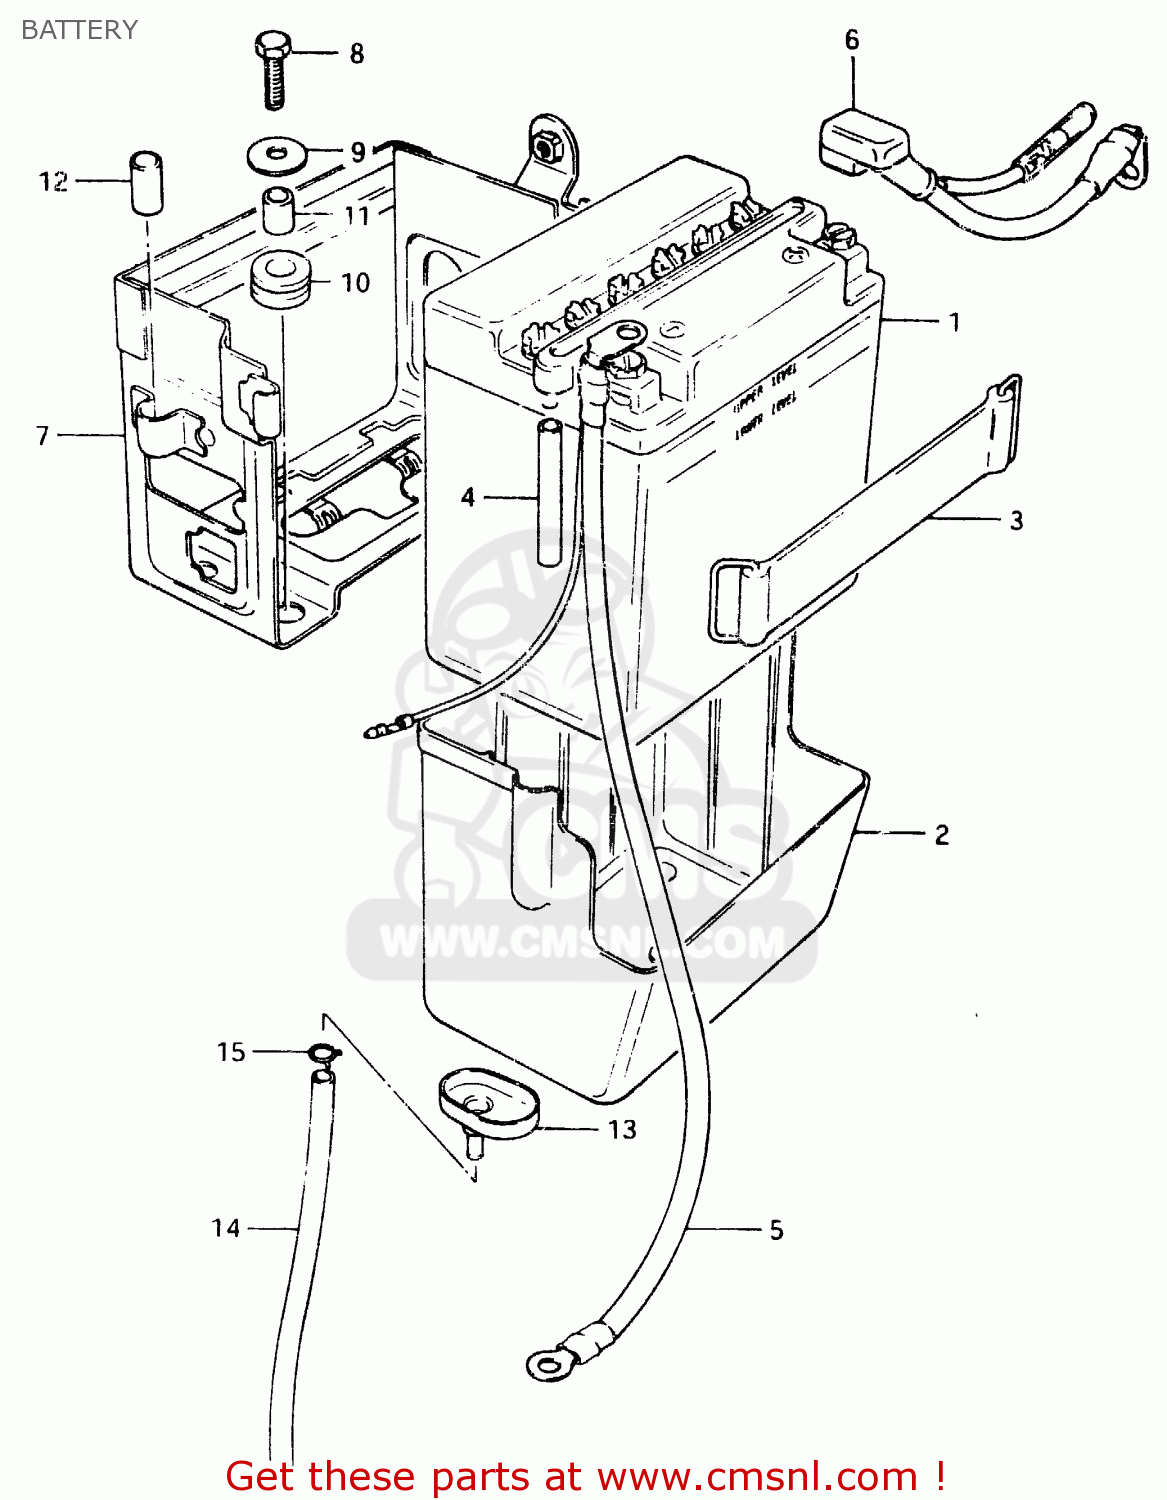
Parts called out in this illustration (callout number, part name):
1	BATTERY ASSY (12V)
2	CASE,BATTERY
3	BAND
4	HOSE, EXHAUST (L:45)
5	LEAD WIRE, (-)
6	LEAD WIRE, (+)
7	HOLDER, BATTERY
8	BOLT L:16
9	WASHER
10	CUSHION
11	SPACER(6.1X9X7.5)
12	CUSHION
13	FUNNEL,BATTERY EXHAUST
14	HOSE,BATTERY EXHAUST
15	CLIP
